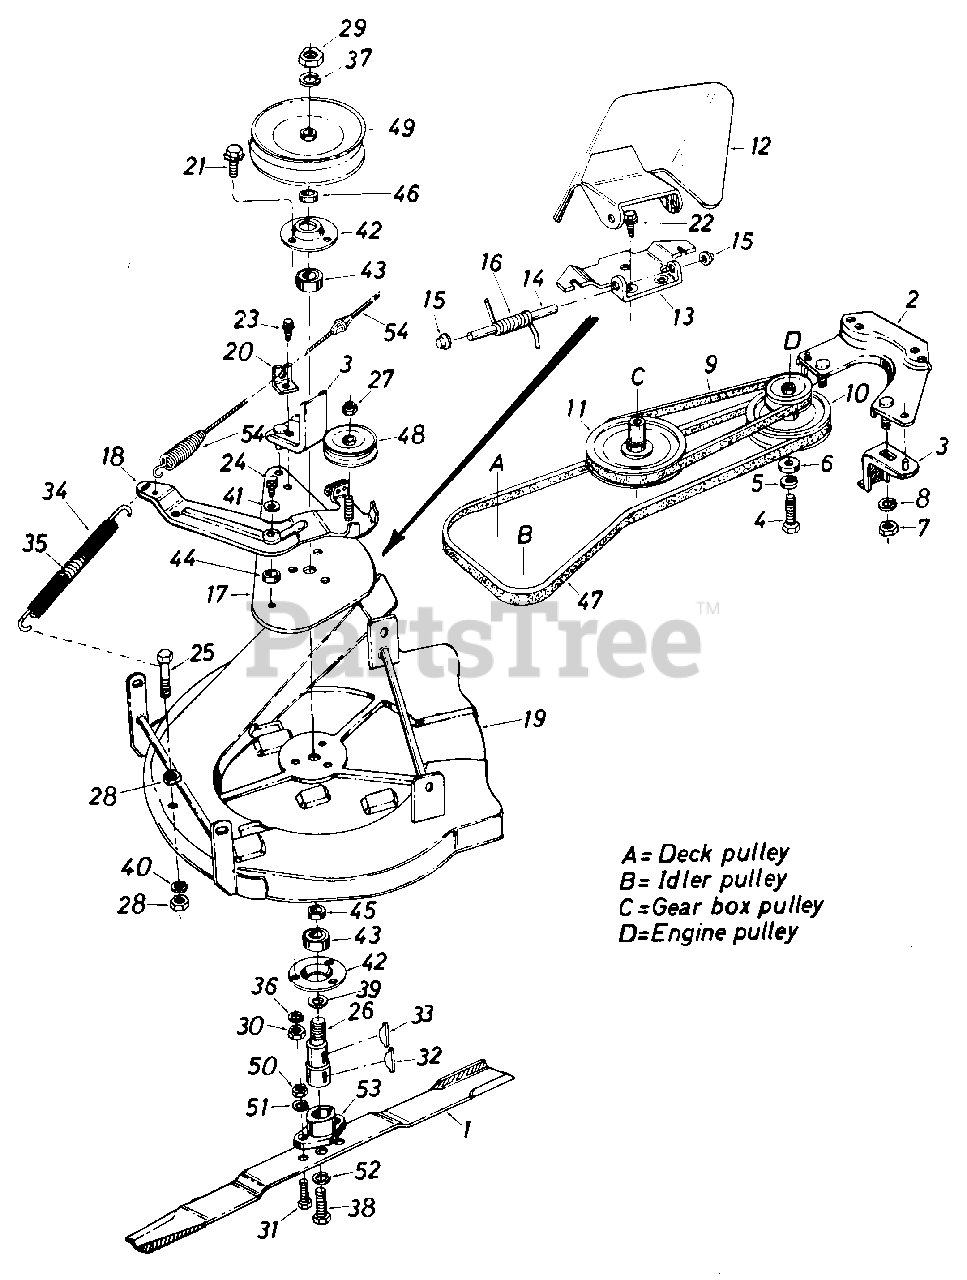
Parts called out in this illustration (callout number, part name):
1	BLADE-26IN
2	GUARD ASSY-BELT-CUP
3	GUARD ASSY-BELT
4	BOLT-3/8 NF X 1"GR5
5	WASHER-LOCK-3/8
6	WASHER-FL-.406ID 1.25OD X.157/.172
7	NUT-HEX 5/16-18
8	WASHER-LOCK-5/16
9	BELT-3V-28
10	PULLEY-ENGINE-TWO STEP
12	COVER-CHUTE-COMP
13	ADAPTER
14	PIN-HINGE
16	SPRING-TORSION
17	PLATE-BELT GUARD
18	BRACKET ASSY-DECK
19	DECK ASSEMBLY-26 IN
20	BRACKET-CABLE SUP
21	SCREW-HEX SEMS 5/16-18 X 1.00
22	SCREW-HEX WASH SF TAPP
23	SCREW-HEX WASH HD 5/16-18X1/2
24	SCREW-HEX 5/16-18 X 10 SPEC
25	SCREW-HEX
26	SPINDLE-BLADE
27	NUT-HEX INS L-3/8-24
28	NUT-HEX CENTER L-1/4-28
29	NUT-HEX CENTER L-5/8-11
30	NUT-HEX 5/16-18
31	SCREW-HEX SPECIAL 5/16-24X1.0
32	KEY-HI-PRO #6-5/32 X 5/8 DIA
33	KEY-3/16 X 5/8
35	SPRING-EXTENSION
36	WASHER-LOCK-5/16
37	WASHER-LOCK-5/8
38	SCREW-HEX 3/8-24 X 1.50 GR.5
39	SHIELD-BRG
40	LOCK WASHER 1/4 DIA
41	WASHER-5/16 X 1.25 X 1.27
42	HOUSING-BRG
43	BEARING-BALL
45	SPACER
47	BELT-V 1/2 X 59
48	PULLEY-V-BELT IDLER
49	PULLEY-TRANS SPLIT .63 ID
50	NUT-5/16-24
51	WASHER-LOCK-5/16
52	WASHER-HDL 3/8
53	KIT-BLADE ADAPTER
54	CABLE-CLUTCH 56.0
